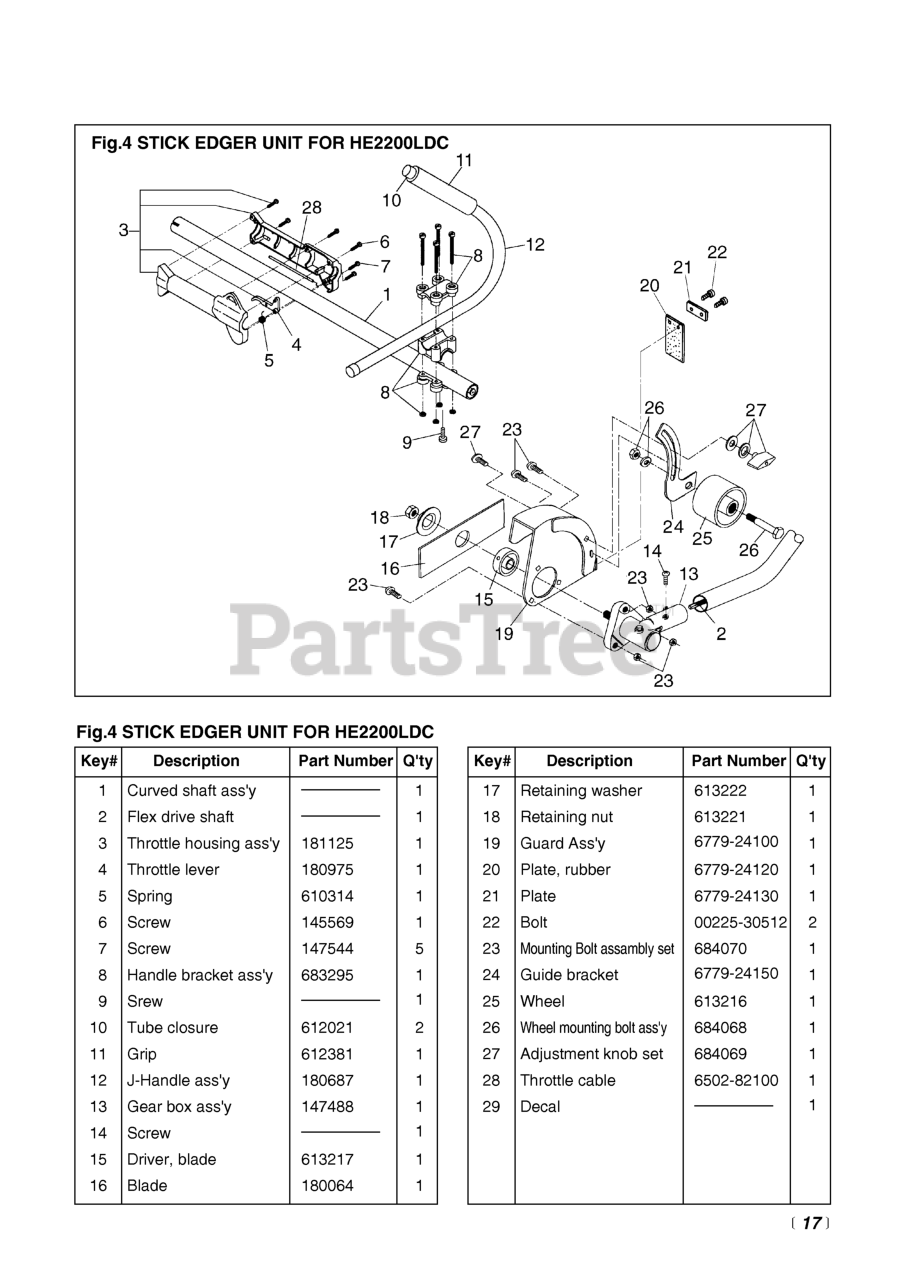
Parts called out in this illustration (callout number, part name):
1	CURVED SHAFT ASSY
2	FLEX, DRIVE SHAFT
4	LEVER, THROTTLE
5	SPRING, THROTTLE TRIGGER
6	SET SCREW, ANTI-ROTATION
8	HANDLE BRACKET ASSEMBLY
9	SCREW
10	CAP
13	GEARCASE ASSEMBLY
14	SCREW
18	NUT, RETAINING
19	GUARD ASSEMBLY
20	PLATE, RUBBER
23	MOUNTING BOLT ASSY SET
26	WHEEL MOUNTING BOLT ASSY
27	ADJUSTMENT KNOB ASSY
28	CABLE COMP (RPLS 6460- )
29	DECAL
